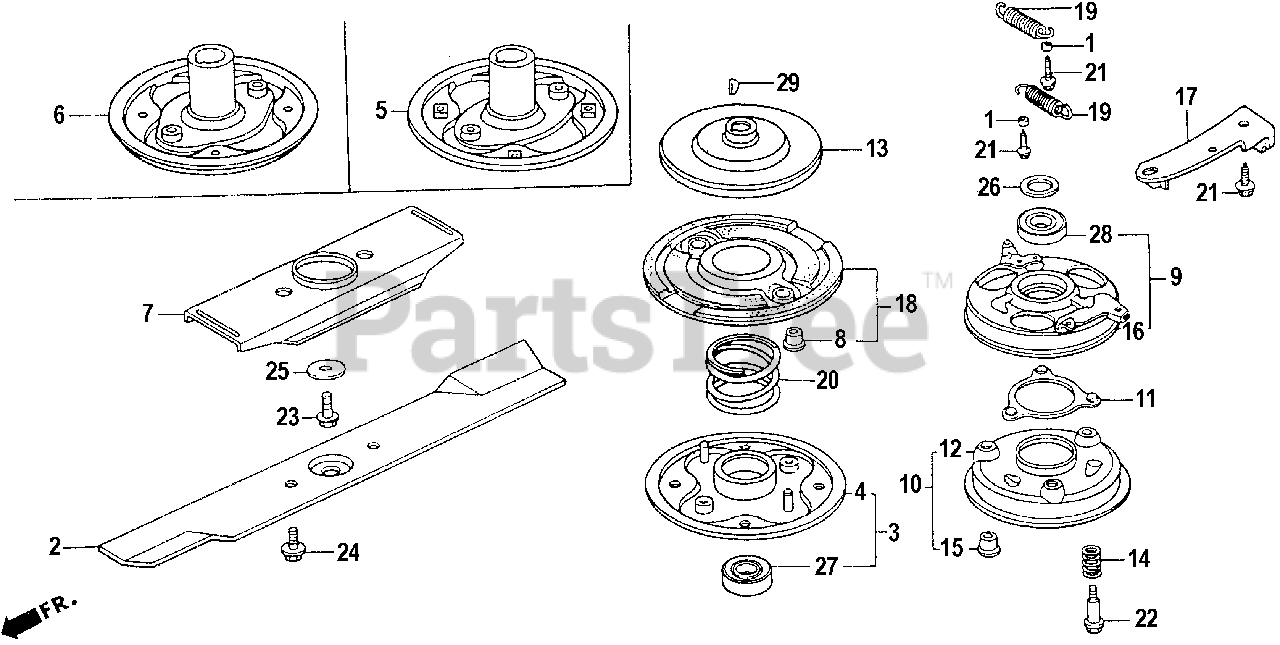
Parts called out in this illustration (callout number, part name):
2	BLADE, ROTARY
5	HOLDER, BLADE
6	HOLDER, BLADE
7	HOLDER, BLADE
23	BOLT, HEX. (10X25)
24	BOLT, HEX. (10X20)
29	KEY, WOODRUFF (16X15)
